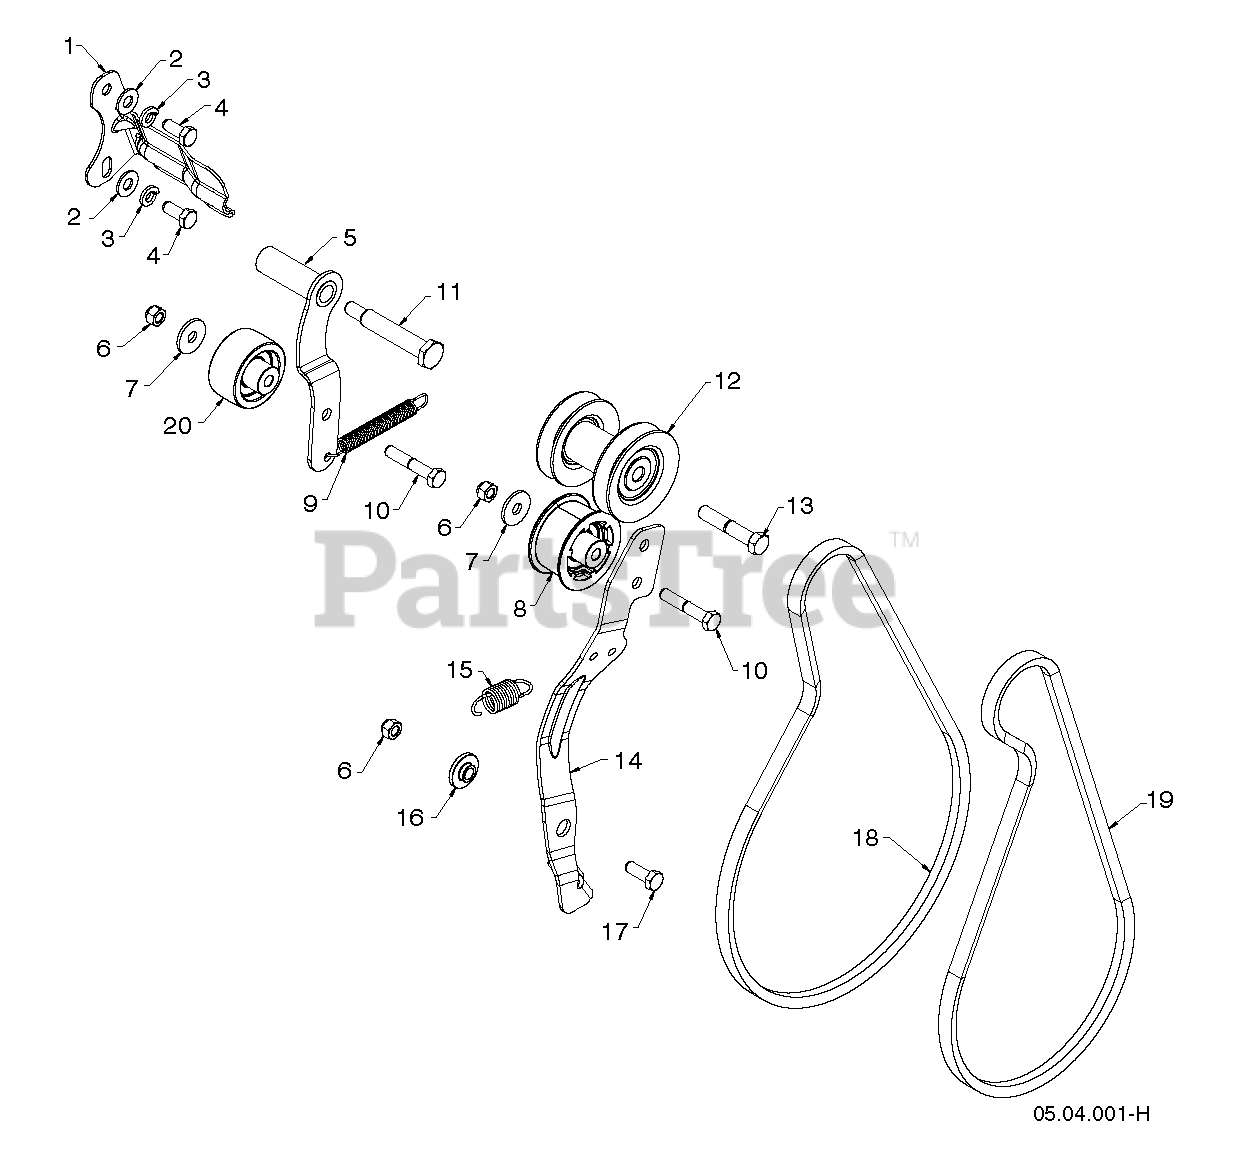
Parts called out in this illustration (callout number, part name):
1	BELT KEEPER BRACKET
2	WASHER M
3	LOCKWASHER
4	SCREW 5/16-24 X .75 GR5
5	ARM IDLER DRIVE WELDMENT_HOT
6	NUT.71038.31-18.HEX.NYLOCK
7	STEEL WASHER
8	PULLEY,IDLER,2.00 W SPA
9	SPRING RETURN IDLER ARM
10	BOLT, HEX 5/16-18X1-3/4
11	BOLT 5/16-24X2.25 HEX HEAD SHO
12	PULLEY.ASM.IMPELLER/DRIVE
13	BOLT.ENGINE.PULLEY
14	ARM.IDLER.AUTO-PH.676
15	SPRING RETURN, IDLER ARM, IMPE
16	BUSHING.BRAKE.ARM
17	BOLT
18	BELT.4L X 38.19
19	LOW CRANK IMPELLER BELT
20	PULLEY.IDLER.FLANG.2.O/SPACER
